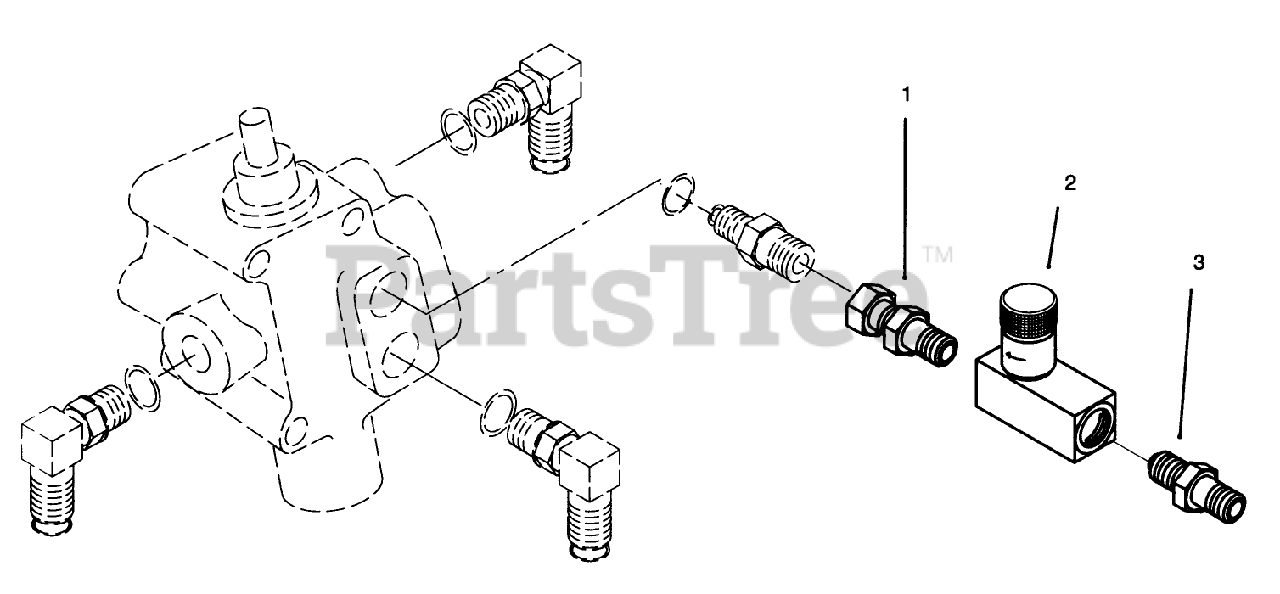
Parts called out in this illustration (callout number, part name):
1	FITTING-SWIVEL STRAIGHT
2	VALVE-ADJUSTABLE FLOW
3	FITTING-MALE
